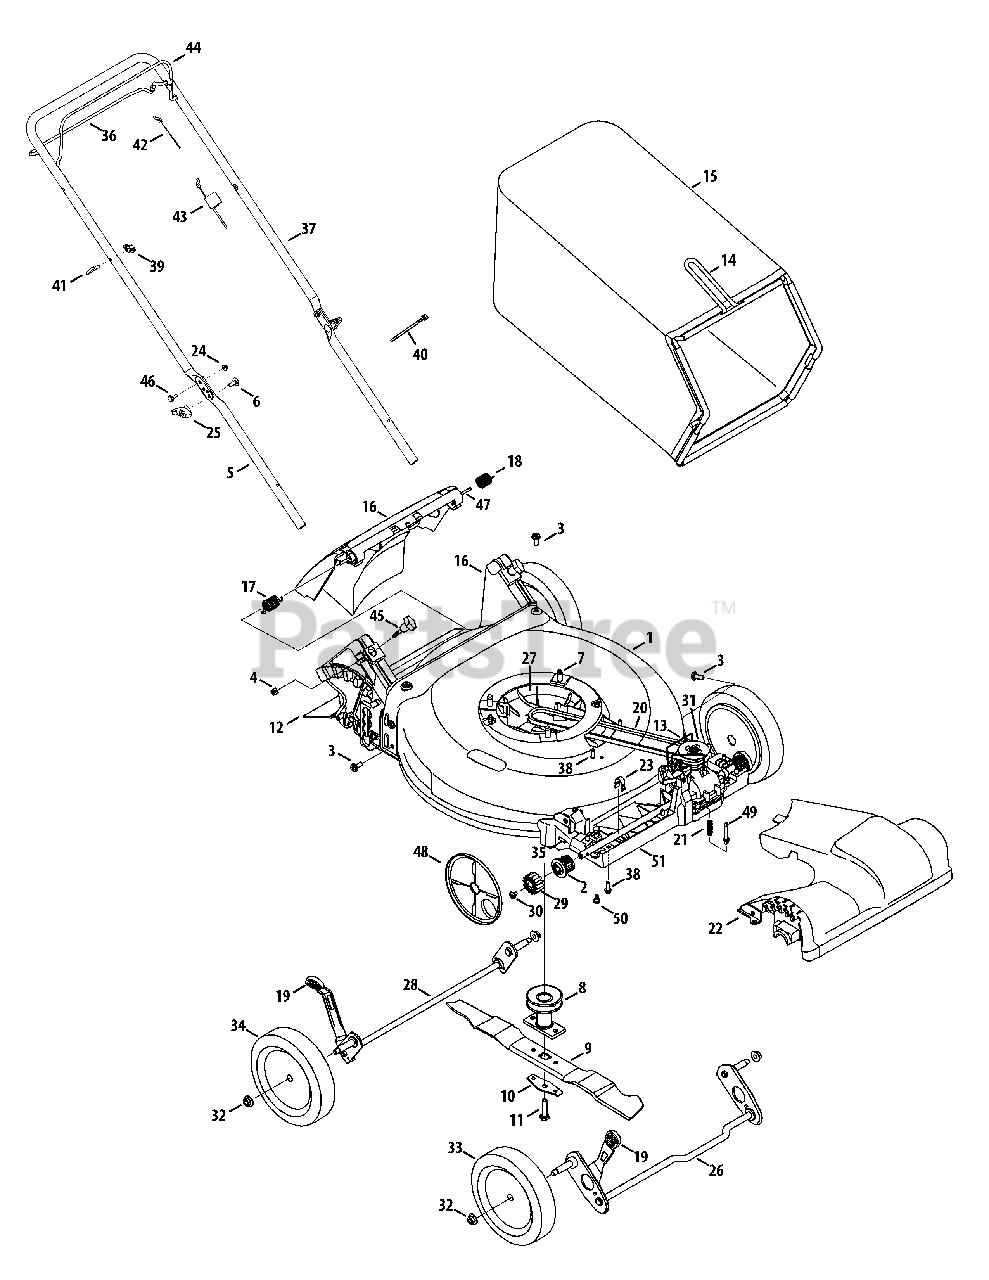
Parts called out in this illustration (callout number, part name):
1	Deck , 21"
2	Bearing Assembly
3	Screw, 5/16-14 x .750
4	Nut, Sq., 1/4-20
5	Lower Handle
6	Carriage Screw ,5/16-18
7	Screw, 3/8-16 x 1.00
8	Blade Adapter
9	Mulching Blade
10	Blade Bell Support
11	Screw, 3/8-24 x 1.50
12	Trailing Shield
13	Transmission Wire
14	Grass Catcher Frame
15	Grass Bag
16	Rear Discharge Door Assembly
17	Torsion Spring - RH
18	Torsion Spring - LH
19	Adjustment Lever Knob
21	Compression Spring
22	Front Cover
23	Front Axle Clip
24	Nut, Flange Lock, 1/4-20
25	Wing Knob
26	Front Axle Assembly
27	Engine Baffle
28	Rear Axle Assembly
29	Spur Gear, 14T - RH
29	Spur Gear, 14T - LH
30	Screw, 1/4-20 x .390
31	Transmission Assembly
32	Flange Lock Nut, 3/8-16
33	Front Wheel
34	Rear Wheel
35	Dowel Pin
36	Drive Control
37	Upper Handle
38	Screw, 1/4-15 x .750
40	Cable Tie
41	Rope Guide
42	Control Cable
43	Drive Cable
44	Blade Control
45	Wing Nut
46	Sldr. Screw, .375 x .126 x 1/4-20
47	Pivot Rod
48	Wheel Dust Cover
49	Spring Body
50	Shoulder Screw, 1/4-20 x 0.50
51	Lower Tray
